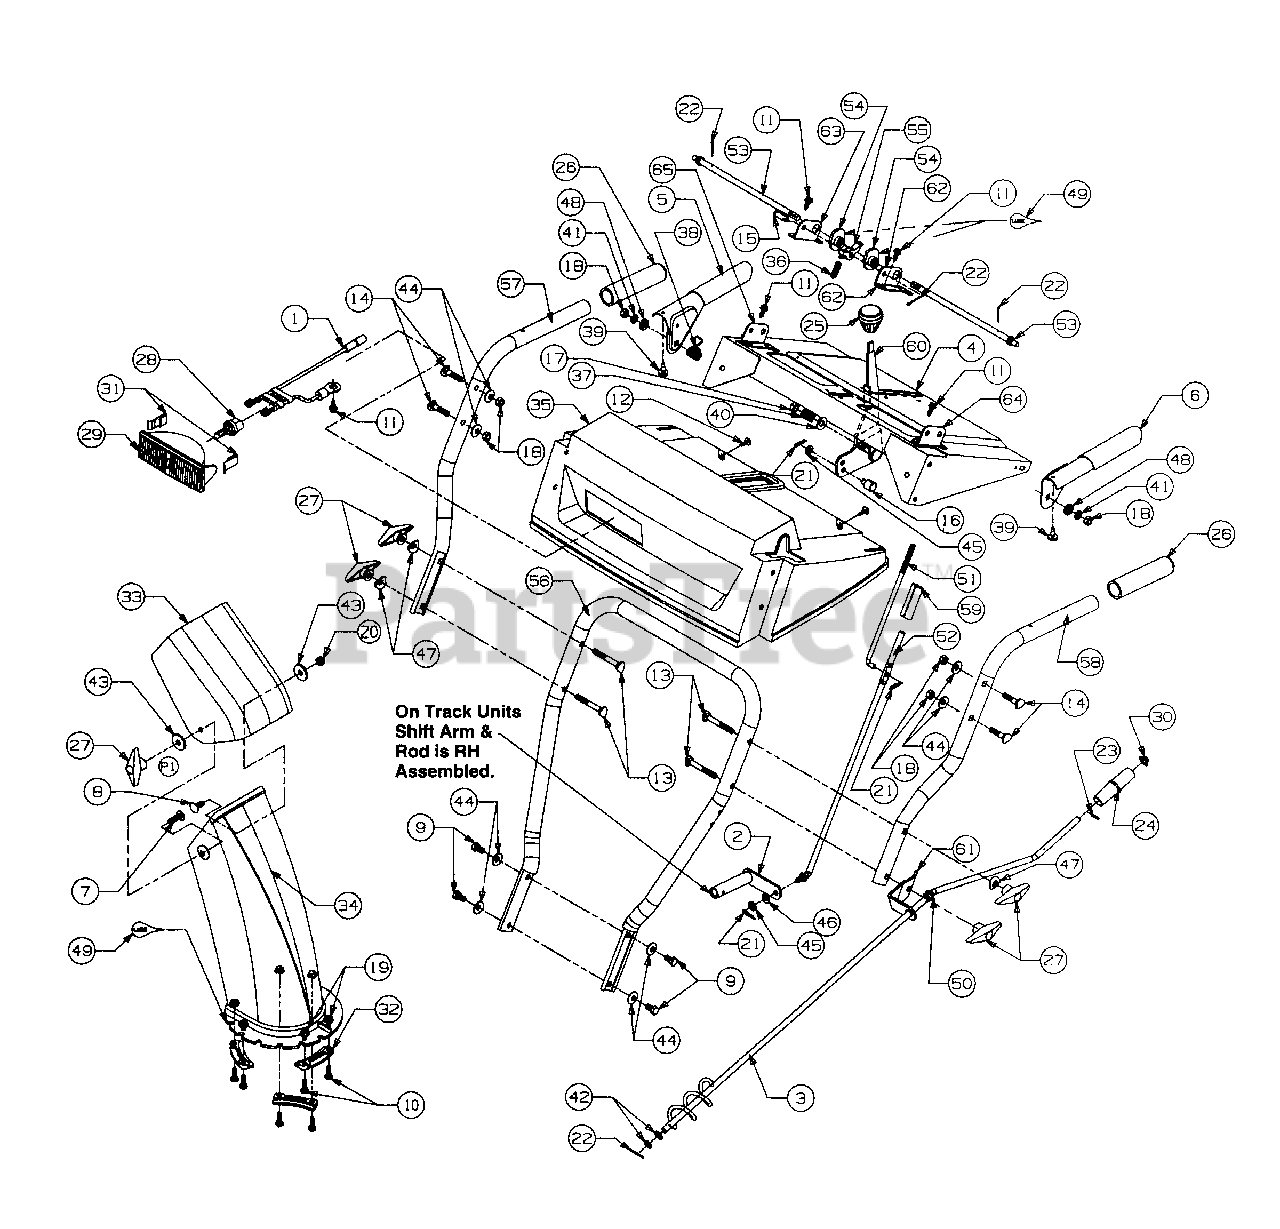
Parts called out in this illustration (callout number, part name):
1	Harness-Snow Thrower
3	Crank-Chute
6	Handle Ass'y. - L.H.
7	Screw-Carriage
8	Screw-Carriage
9	Screw-Hex
10	Screw-Hex
11	Screw-Hex
12	Screw-Hex
13	Bolt-Carriage
14	Bolt-Carriage
15	Pin-Clevis
16	Ferrule
17	Nut-Hex
18	Nut-Hex
19	Nut-Hex Lock
20	Nut-Hex Lock
21	Pin-Cotter
22	Pin-Cotter
23	Pin-Roll
24	Knob-Chute Crank
25	Knob-Shift
27	Knob-Wing Nut
28	Lamp
29	Housing-Lamp
30	Cap Push
31	Clip-Retaining
32	Keeper Chute
33	Chute-Upper
34	Chute-Lower
35	Panel-Handle
36	Spring
37	Spring
38	Spring
39	Bumper
40	Washer-Bell
41	Washer-Lock
42	Washer-Flat
43	Washer
44	Washer-Bell
45	Washer-Flat
46	Washer-Spring
47	Washer-Saddle
48	Washer
49	Lubricant
50	Bushing-Plastic
51	Rod-Shift Upper
52	Rod-Shift Lower
53	Rod-Cam
54	Cam-Handle Lock
55	Pawl-Handle Lock
59	Connector-Clutch Rod
60	Handle-Shift
